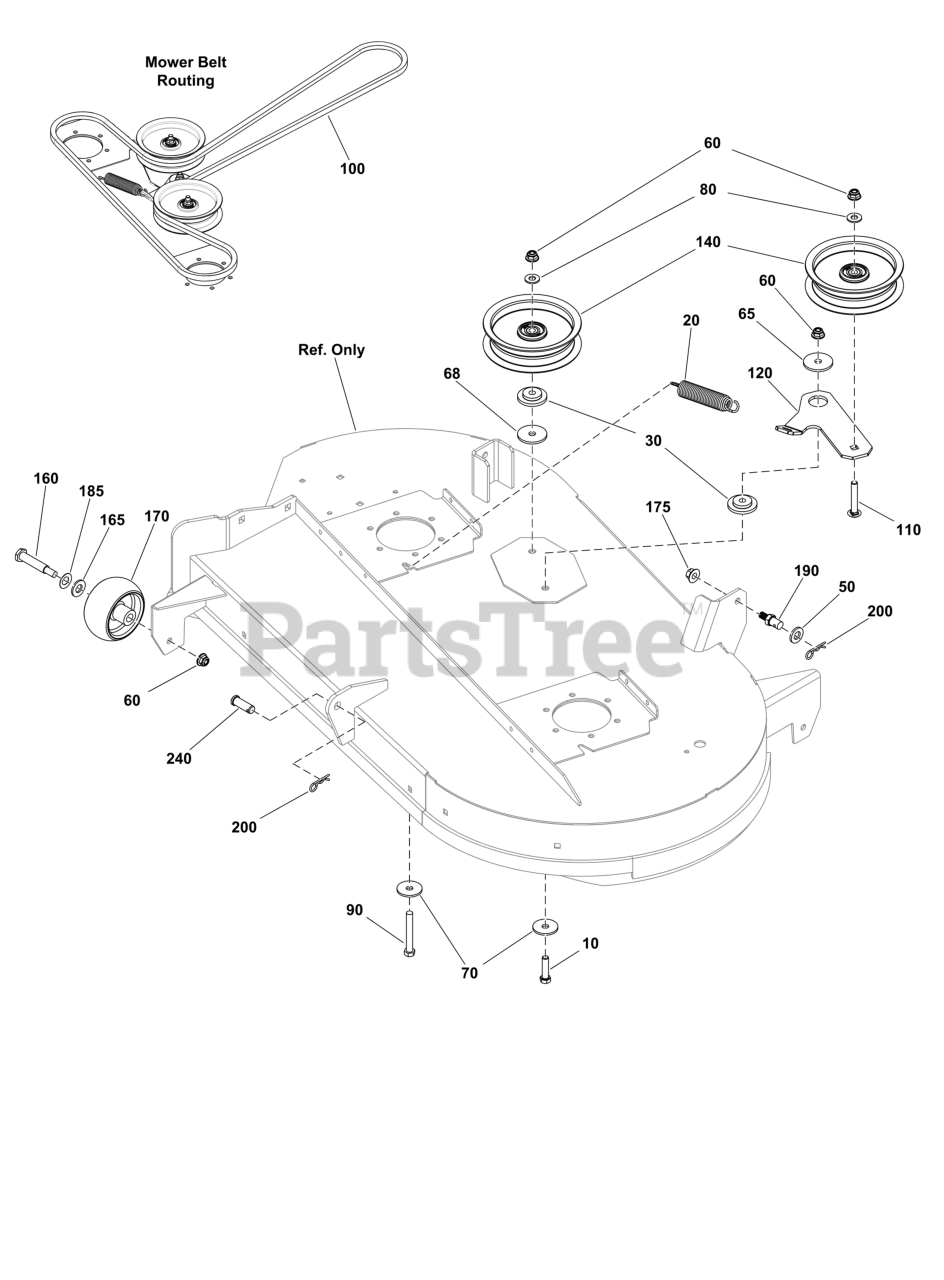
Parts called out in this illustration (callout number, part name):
10	CAPSCREW,3/8-16X1.5
20	SPRING, Extension
30	SPACER, IDLER
50	WASHER, 0.516IDX1OD
60	NUT, 3/8-16 HEX NYLOCK
65	WASHER, .41 X 1.75 X
68	WASHER, .41 X 1.75 X
70	WASHER, .406X1.5X.12
80	WASHER, FLAT
90	BOLT, 3/8-16 X 2-3/4"
100	BELT, 113.0 Effective Length
110	RHSSNB, 3/8-16 X 2-1/
120	ARM, Idler
140	PULLEY, Flat Idler
160	BOLT-WHEEL 3/8-16X2.7
165	WASHER, 1/2" SAE
170	GAUGE WHEEL
175	NUT, Hex Flange, MAC Lock Large, 3/8-16
185	WASHER,SPRING .52X.99
190	PIN, 3/8-16
200	HAIR PIN, 3/32X1-1/2
240	CLEVIS PIN, 1/2 X 1.3
